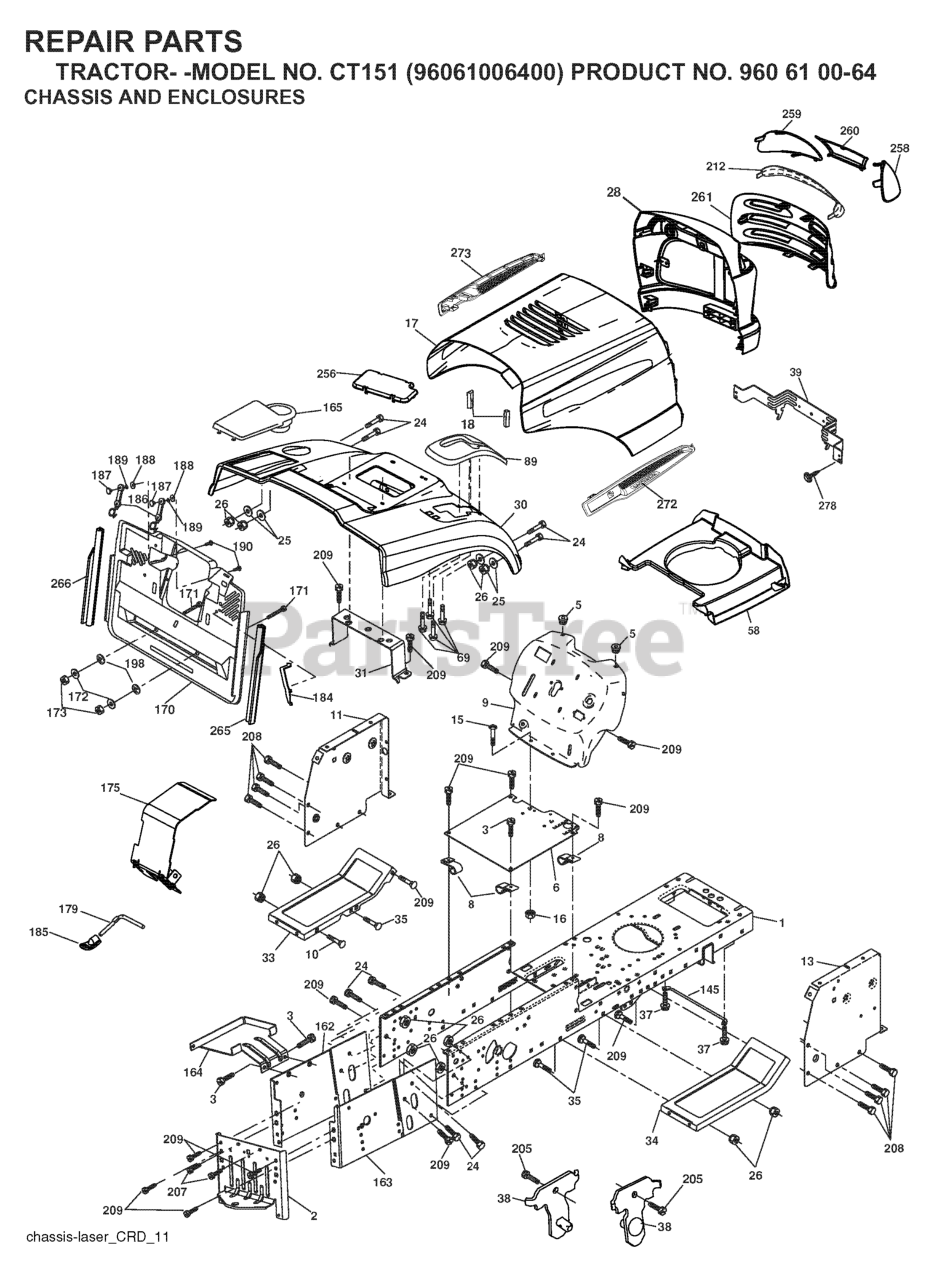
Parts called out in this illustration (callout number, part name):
2	DRAWBAR
3	SCREW 3/8-16X3/4
5	BUMPER.RUBBER.HOOD
6	PLATE
8	CLIP,INSULATOR
10	BOLT D
11	PANEL.DASH.LH.LTX
13	PANEL ASM, DASH RH
15	Screw, Machine, Truss Head 5/16-18 UNC x 3/4
16	NUT
17	VENT.HOOD.LASER.III
18	BUMPER.HOOD.LARGE.1.75"
25	WASHER
26	NUT
30	CONSOLE.CRD.AUTO.GRY
31	BRACKET SUPPORT FENDER
33	FOOTREST PNT LH
34	FOOTREST PNT RH
37	Screw 5/16-18 x 1/2 Hex, Self Tapping 5/16-18 x 1/2
38	BRACKET ASM PIVOT MOWER REAR
39	BRACKET PIVOT LASER
69	SCREW.HI-LO.CONSOLE
145	ROD PIVOT CHASSIS/HOOD
162	BRACKET
163	BRACKET EXTEN CHASSIS RH CRD
165	RP.COVER.BATTERY.CRD.GREY
172	WASHER
175	DOOR TRAP
179	ROD PIVOT FBI
184	BRACKET.ACTUATOR.BAGGER.SRD
186	LATCH ASSY
187	WELDNUT
189	LOCKWASHER #10
190	SCREW
207	SCREW, 5/16-18 X 1/2
208	SCREW 3/8-16X1/2
209	SCREW, 3/8-16X3/4
212	INSERT.LENS.REFLECTIVE
256	COVER FENDER CRD
258	LENS LH
259	LENS LH
260	COVER.LENS.HUSQ.LASER
265	SEALING
266	SEALING
272	VENT.HOOD.LASER.
273	VENT.HOOD.LASER.
278	SCREW
